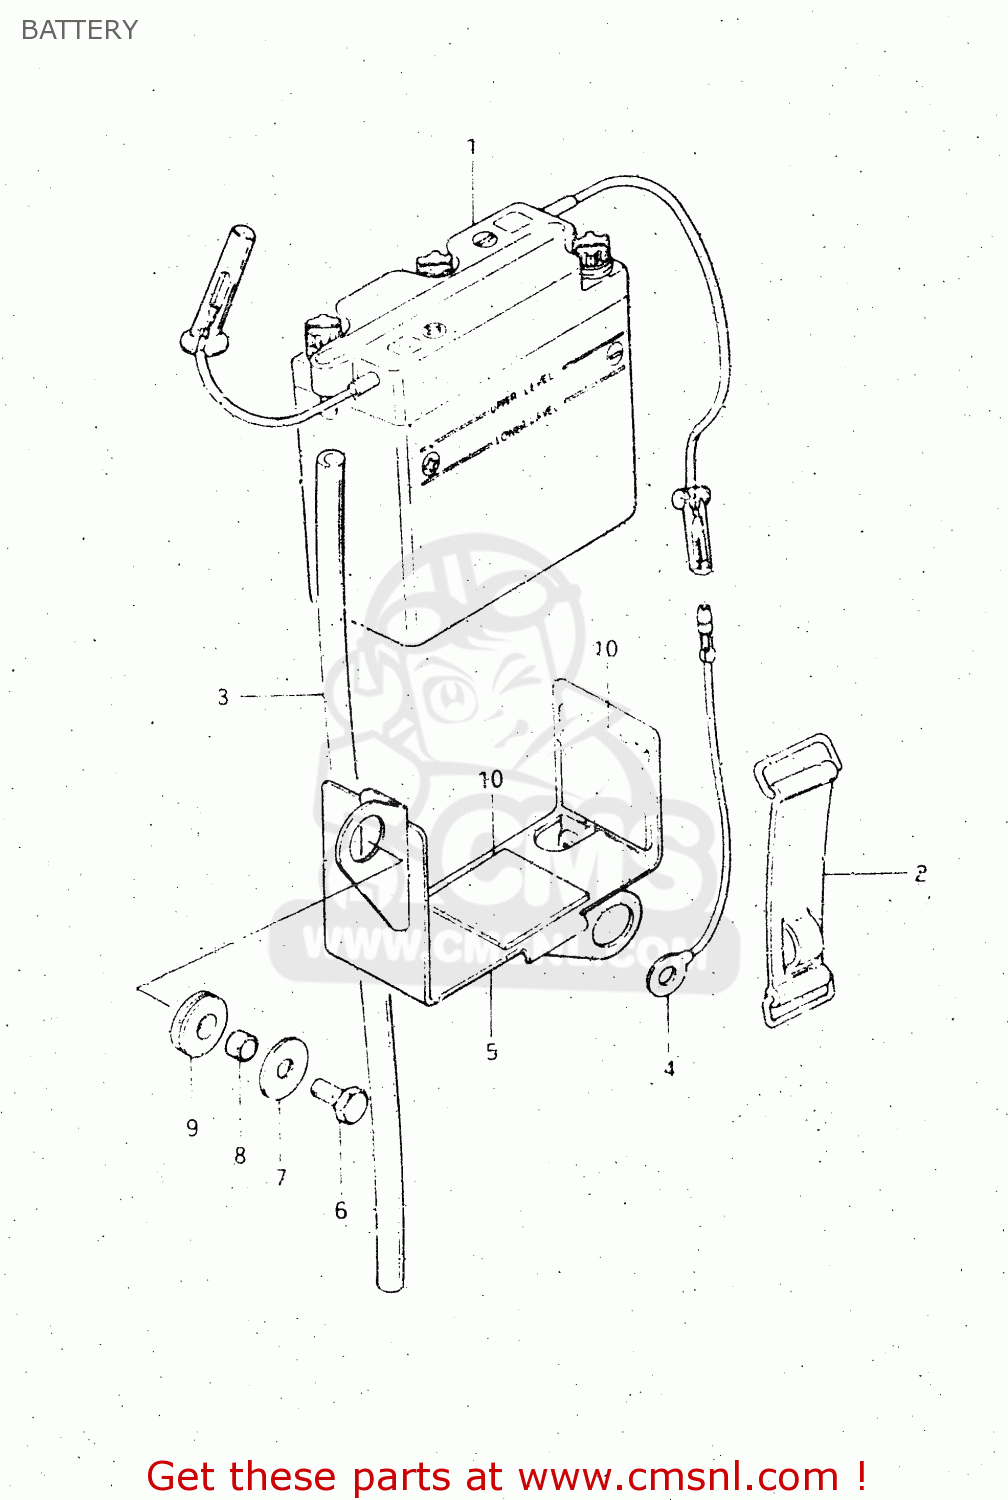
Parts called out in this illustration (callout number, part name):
1	BATTERY (6V, 4AH)
2	BAND
3	HOSE,BATTERY EXHAUST
4	LEAD WIRE
5	HOLDER,BATTERY
6	BOLT, UPPER
7	WASHER (6.5X20X1.2)
8	SPACER(6.1X9X7.5)
9	CUSHION
10	PROTECTOR,BATTERY
